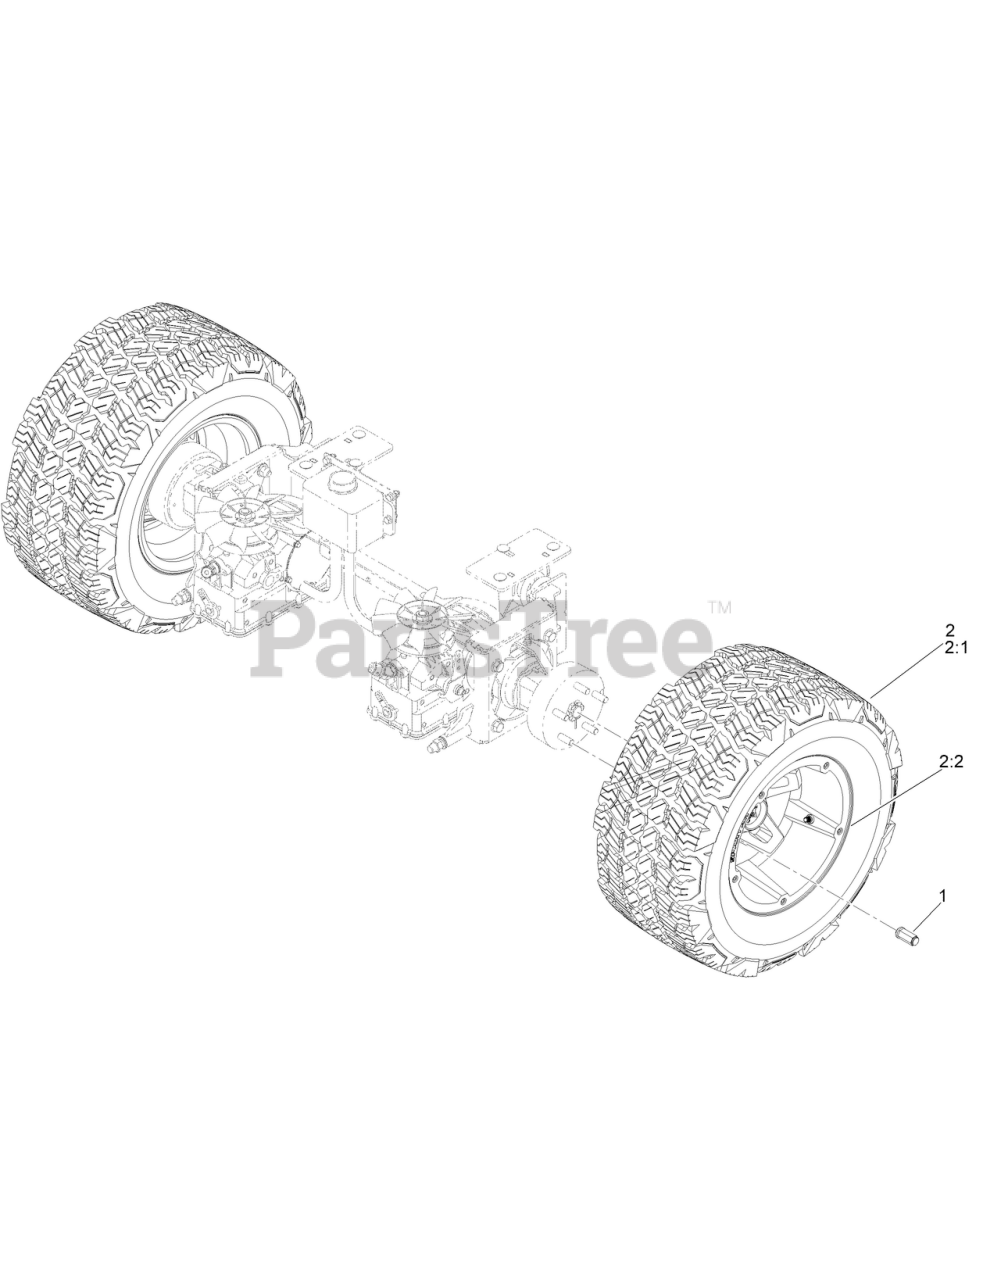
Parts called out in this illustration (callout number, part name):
1	LUG NUTS
2	2019 MWR XD WHEEL AND 24X14-R12 TIRE
2:1	24 X 14 R12 SOFT RIDE RADIAL TIRE ONLY
2:2	12 X 8.5 416 STYLE WHEEL ONLY
